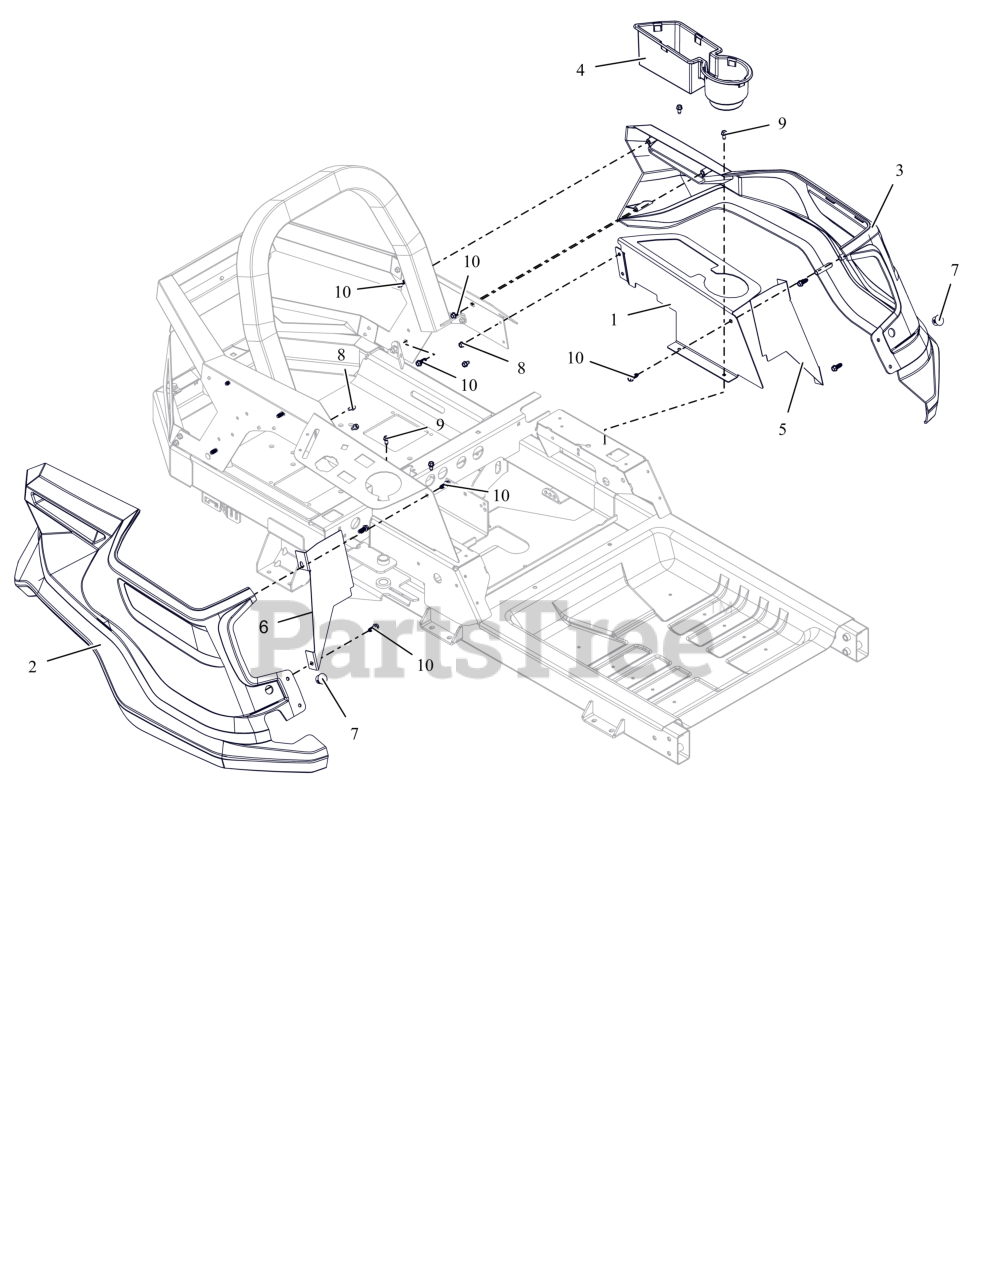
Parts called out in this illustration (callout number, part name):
1	PANEL, LEFT SIDE FENDER MOUNT
2	FENDER, RH IKON
3	FENDER, LH IKON
4	INSERT, CUP/STORAGE HOLDER
5	PLATE, LH BLOCKER
6	PLATE, RH BLOCKER
7	PLUG, HOLE .75 (BLACK)
8	SCR,TAP .25-20X.375 HWH TR ZCC
9	SCR-TAP .25-20X.50 HWH ZCC
10	SCR-.312X.75 #14H H/W/H H/L CZ
